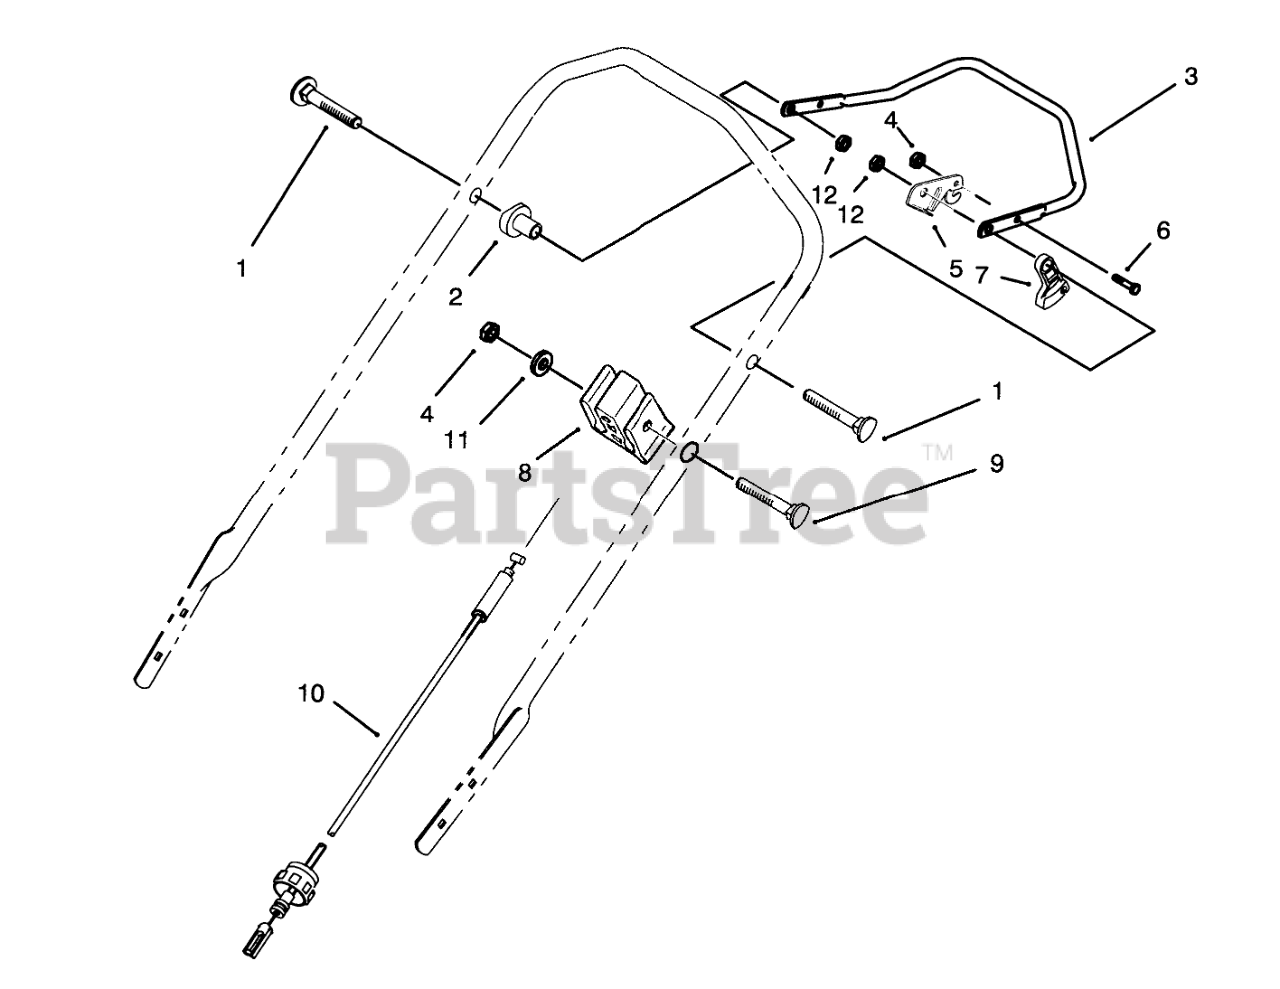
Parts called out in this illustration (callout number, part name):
1	SCREW-HANDLE
2	SPACER-SUPPORT
3	Bar-Control
4	NUT-LOCK, NI
5	LEVER-CONTROL
6	SCREW-HH
7	LEVER-TRACTION
8	SUPPORT-CABLE
9	SCREW-HANDLE
10	TRACTION CABLE
11	WASHER-FLAT
12	NUT-LOCK, NI
